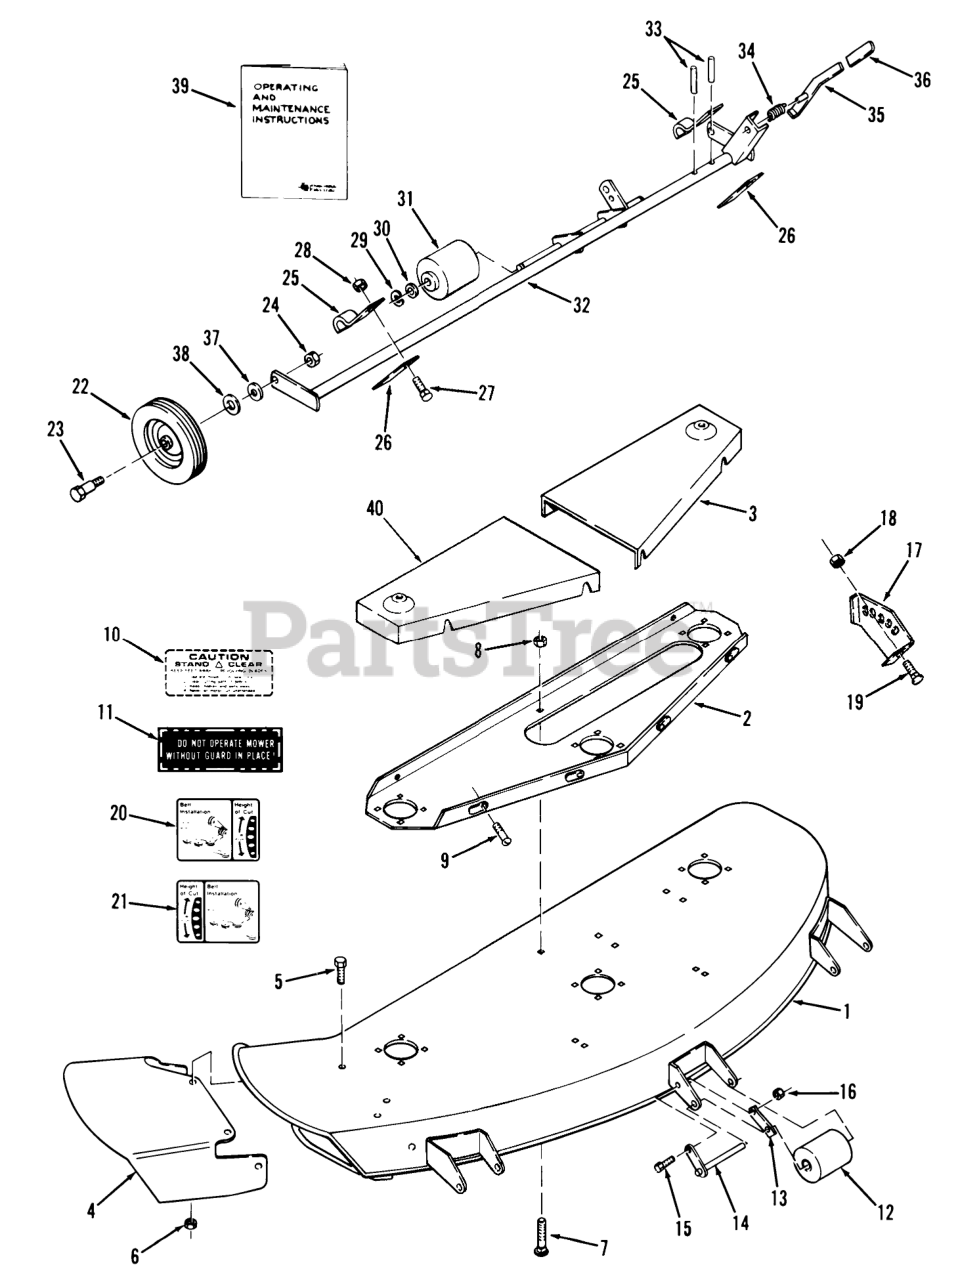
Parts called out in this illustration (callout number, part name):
1	ASSY-48 MOWER DEC R
1	ASSY DECK 42"MOWE R
2	Channel
3	Belt Cover LH
4	Chute Extension
5	Bolt
6	Nut
7	Bolt-Carriage
8	NUT
9	Screw
9	Bolt
10	Caution Decal
11	Decal-Caution
12	Roller
13	SPRING ROLLER STOP
14	Roller Shaft
15	H H C S
16	Nut
17	LH QUADRANT R
17	Quadrant
18	NUT
19	Bolt
20	DECAL-HEIGHT & BELT
21	DECAL-HEIGHT & BELT
22	Wheel 6 x 1.75
23	BOLT-SHOULDER
24	Nut
25	Machine Bolt
26	Bar
27	Bolt
28	NUT
29	E Ring
30	Washer
31	Roller
32	Gage Wheel Support
32	Support Ass-y. Gage Wheel
33	PIN-SPIROL
34	SPRING-COMPRESSION
35	Lever
35	LEVER ASSY R
37	WASHER
38	WASHER
39	Operating and Maintenance Instructions
40	Belt Cover RH
